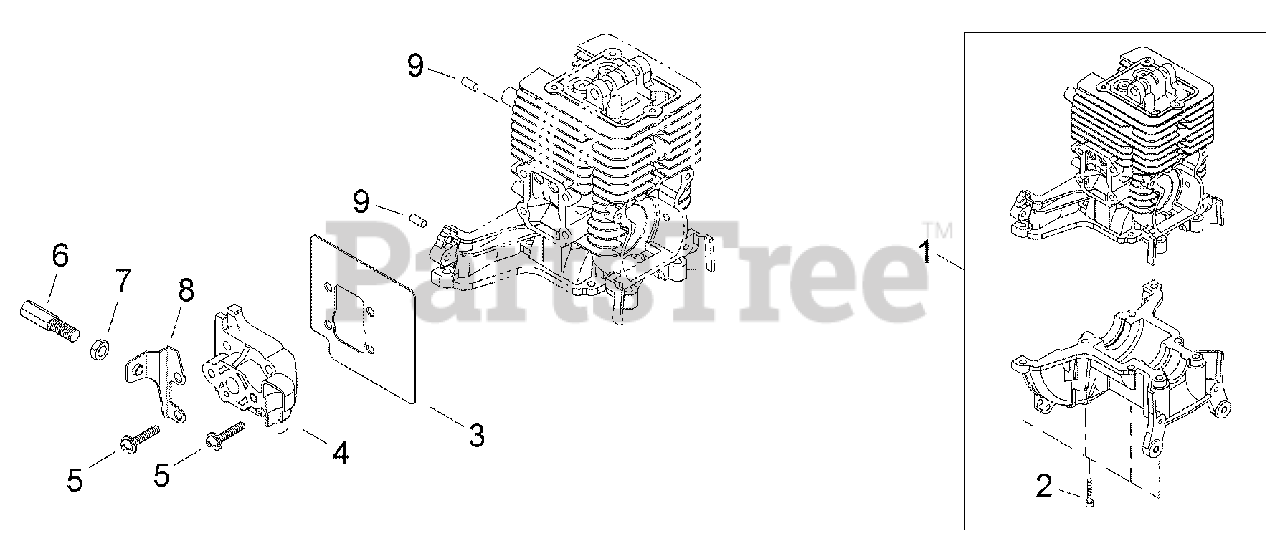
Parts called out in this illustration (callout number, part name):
1	CYLINDER BLOCK SET
2	SCREW - 5X16
3	DEFLECTOR, HEAT
4	VALVE, REED
5	SCREW - 5X25
6	NUT, CABLE ADJUST
7	LOCKNUT - 6
8	BRACKET, THROTTLE CABLE
9	PIN - LOCATING
